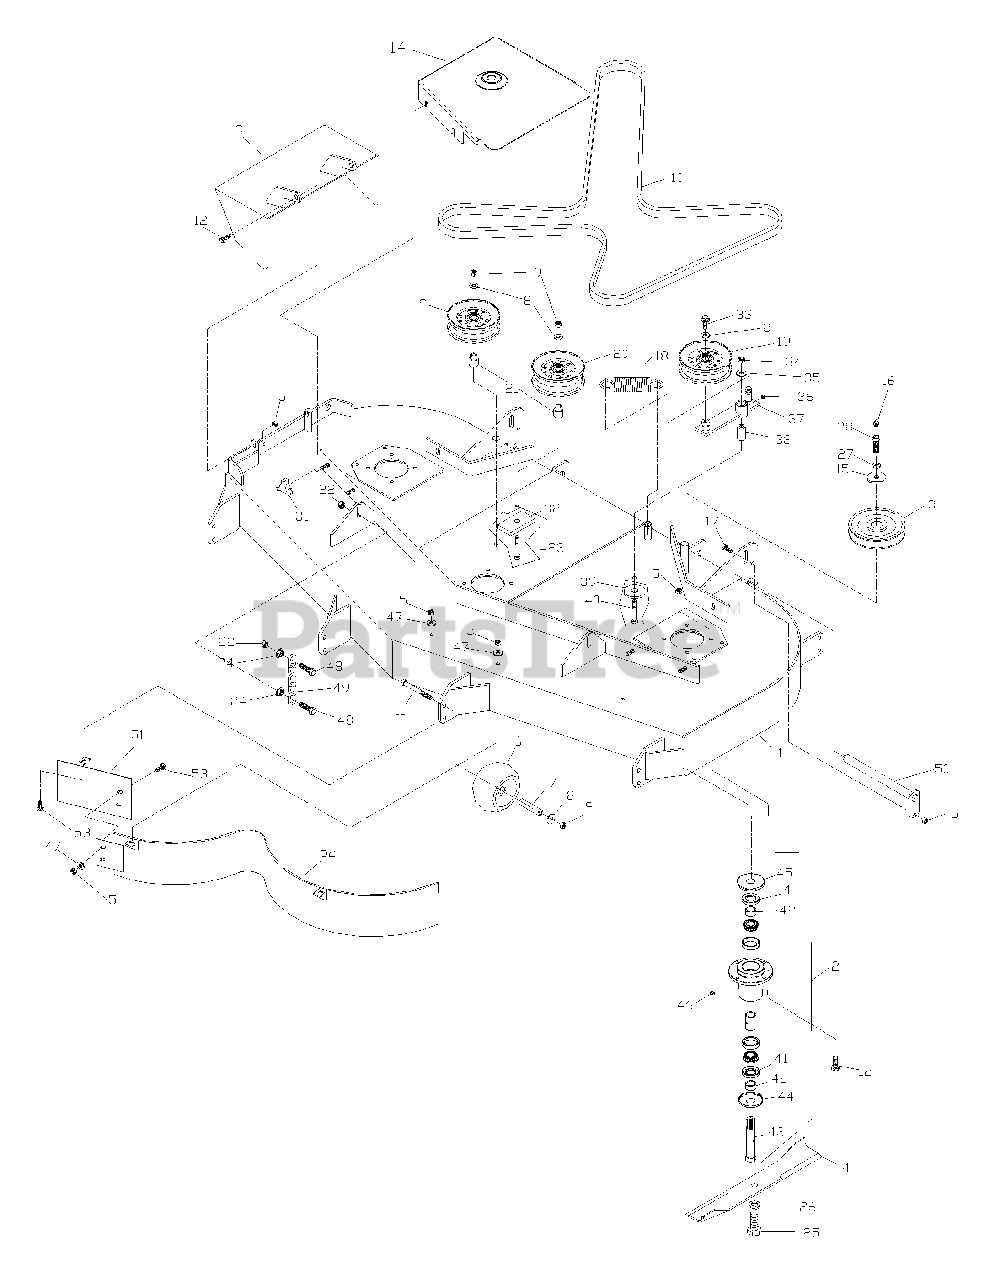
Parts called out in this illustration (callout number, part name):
1	DECK W/DECALS
2	CUTTER HOUSING ASM.
3	PULLEY
5	NUT 5/16 LOCK
8	3/8 FLAT WASHER
9	NUT 3/8 LOCK
10	BELT
11	HCS 3/8 X 3.5
12	HCS 5/16 X 1.25
13	DISCHARGE CHUTE
14	BELT SHIELD RT.
16	ZERK
17	HCS 5/16 X .750
19	PULLEY 1.31
20	PULLEY 1.62
21	IDLER BUSHING
22	NUT 7/16 LOCK
23	HCS 3/8 X 2.5
24	NUT 7/16 WHIZ
25	HCS 5/8F X 1.25
26	WASHER 5/8 LOCK
27	7/16 LOCK WASHER
28	HCS 7/16F X 1.5, SPECIAL
32	PAD
33	HCS 3/8 X 1.0 SERR.
34	NUT 1/2 NYLOC
35	WASHER 1/2 FLAT
36	ZERK
38	PIVOT BUSHING
39	SUPPORT WASHER
40	HCS 1/2 X 3.25
41	SHAFT SEAL
43	MINI SPINDLE
44	DUST CAP, BOTTOM
45	DUST CAP, TOP
46	GREASE POPET
47	5/16 FLAT WASHER
48	HCS 7/16 X 1.5
49	LIFT CHAIN
51	BAFFLE , CENTER
52	BAFFLE, MAIN
53	RHSNB 5/16 X 5/8
